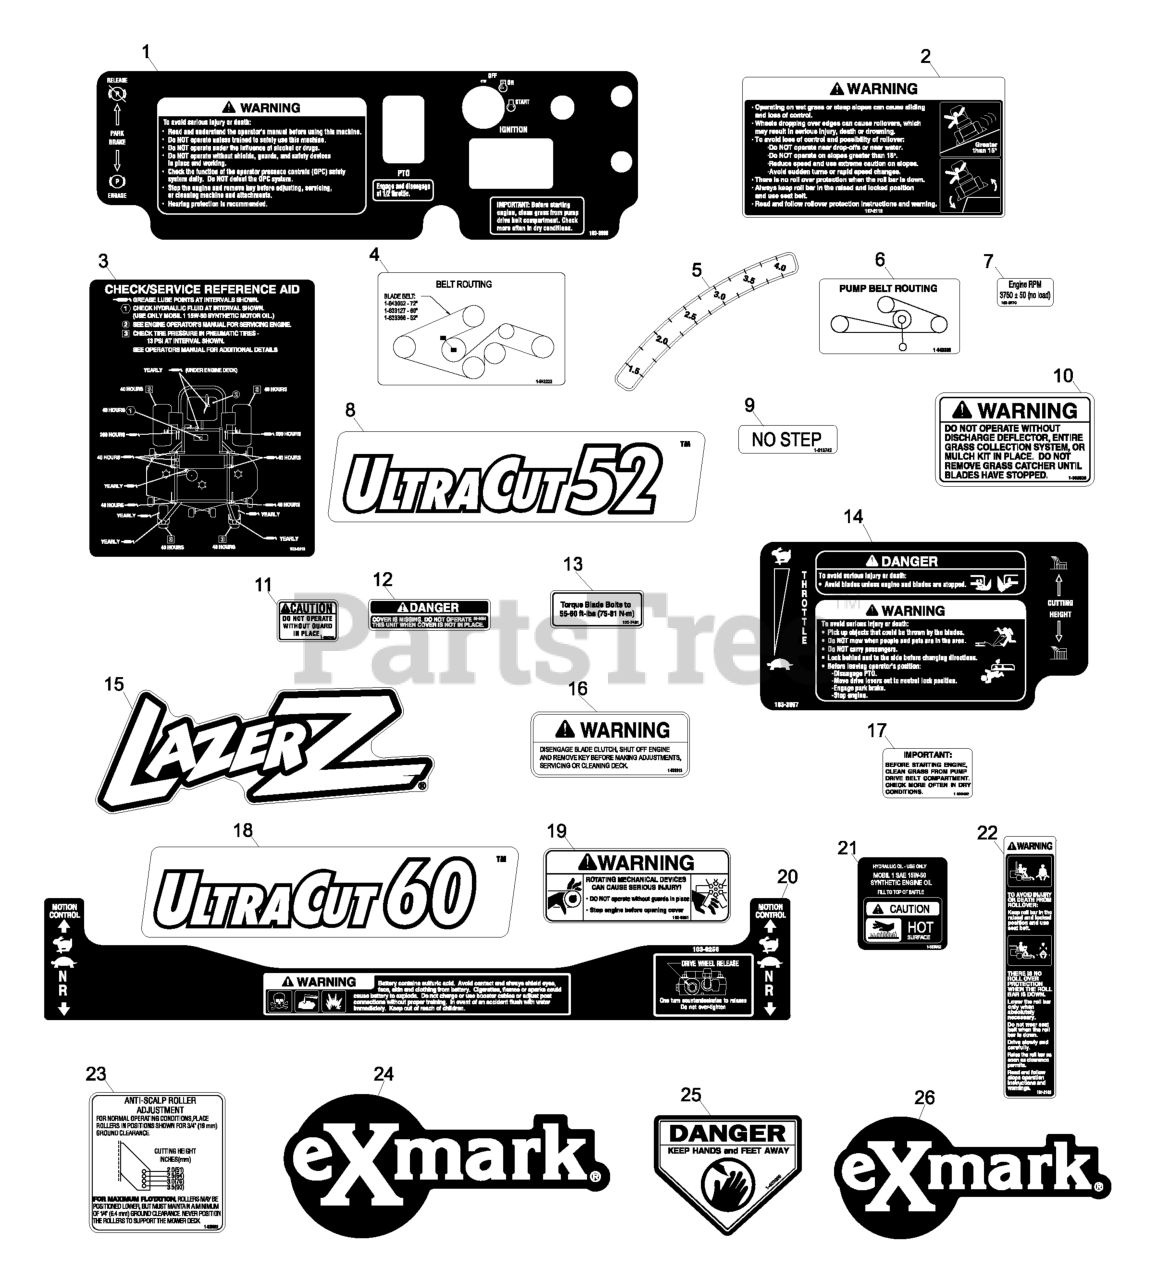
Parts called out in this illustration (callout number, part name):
1	DECAL, CONSOLE AS
2	DECAL-WARNING
3	DECAL,CHECK SERVICE LZ
4	DECAL,BELT ROUTING
6	DECAL-ROUTING, BELT
8	DECAL,ULTRACUT 52
9	DECAL,NO STEP
10	DECAL-WARNING, DISCHARGE
11	DECAL-GUARD
12	DECAL-COVER, MISSING
14	DECAL, CONSOLE THROTTLE A
15	DECAL,LAZER MODEL
16	DECAL,WARNING
17	DECAL-IMPORTANT
18	DECAL,ULTRACUT 60
19	DECAL-DEVICES, ROTATING
22	DECAL-WARNING, FOLDING RO
23	DECAL,ANTISCALP
24	DECAL,EXMARK LOGO
25	DECAL-DANGER
26	DECAL,EXMARK LOGO
